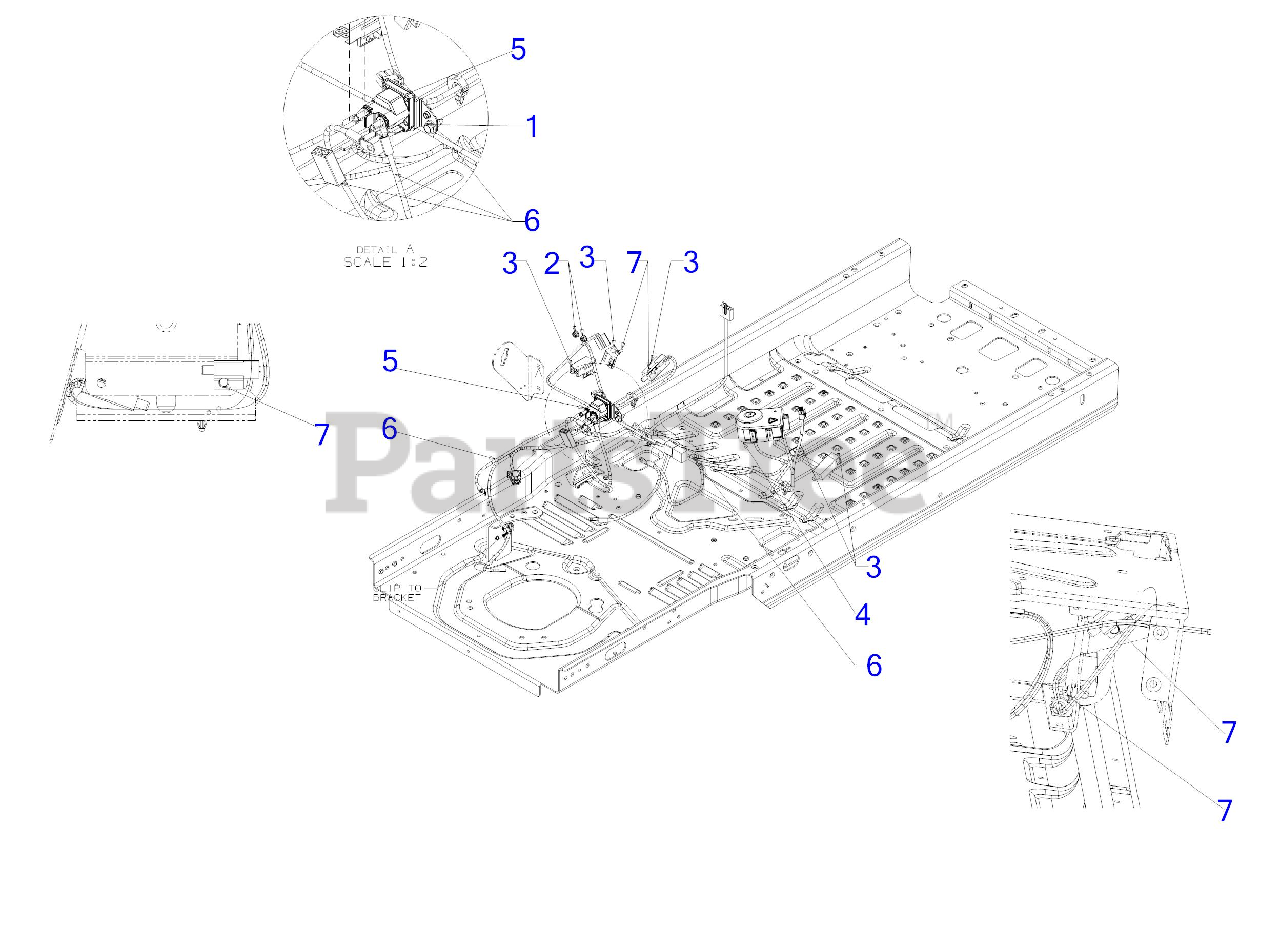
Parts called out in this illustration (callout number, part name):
1	SCREW 1/4-20X.625
2	FLANGE LOCK NUT
3	INTERLOCK SWITCH (NO/NC)
4	IGNITION MODULE SWITCH RMC (MAN PTO BLK)
5	SOLENOID-12V 100A
6	MAIN HARNESS (MANUAL PTO)
7	SHOULDER SCREW
